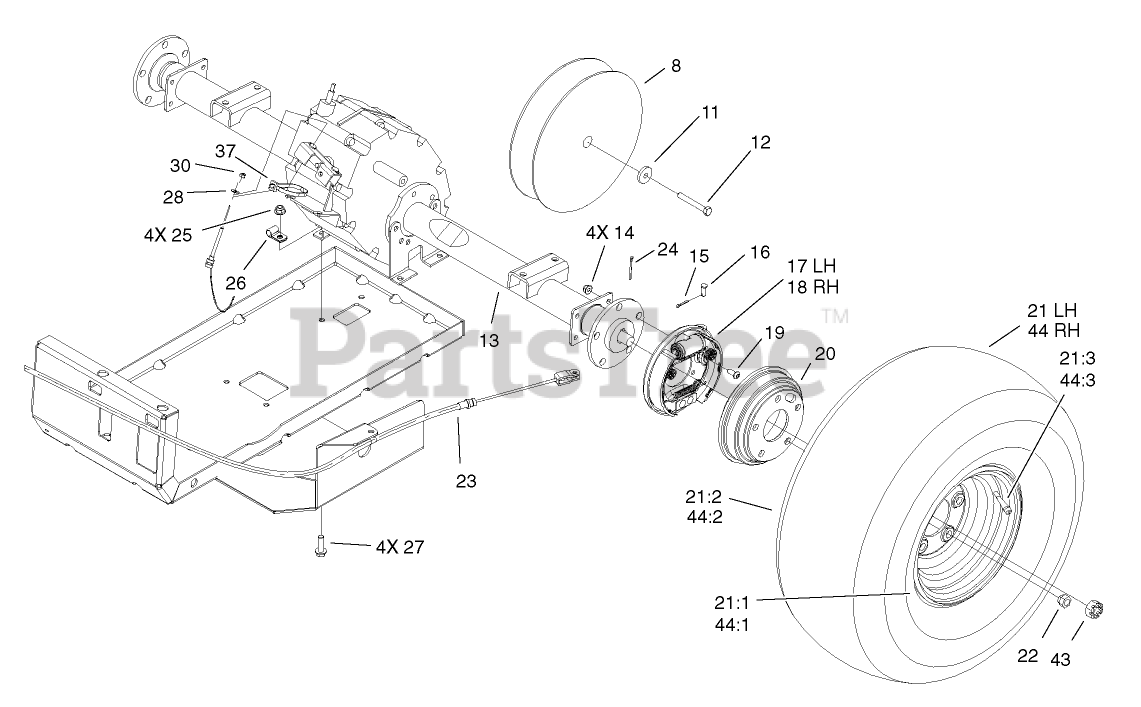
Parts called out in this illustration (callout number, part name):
11	WASHER-STEPPED
12	SCREW-HH
13	TRANSAXLE(SHIP TRUCK)
14	NUT-HF, NI
15	PIN-COTTER
16	PIN-CLEVIS
17	LH BRAKE ASM
18	RH BRAKE ASM
19	SCREW-HSBH
20	DRUM-BRAKE
21:1	WHEEL-5 BOLT
22	NUT-LUG
23	CABLE-BRAKE, PARK
24	PIN-COTTER
25	NUT-HF, NI
26	CLAMP-R
27	SCREW-HHF
28	WASHER-PLAIN
30	NUT-LOCK, NI
37	TIE-CABLE
43	NUT-CASTLE
44	Loose Parts Package
44:1	WHEEL-5 BOLT
